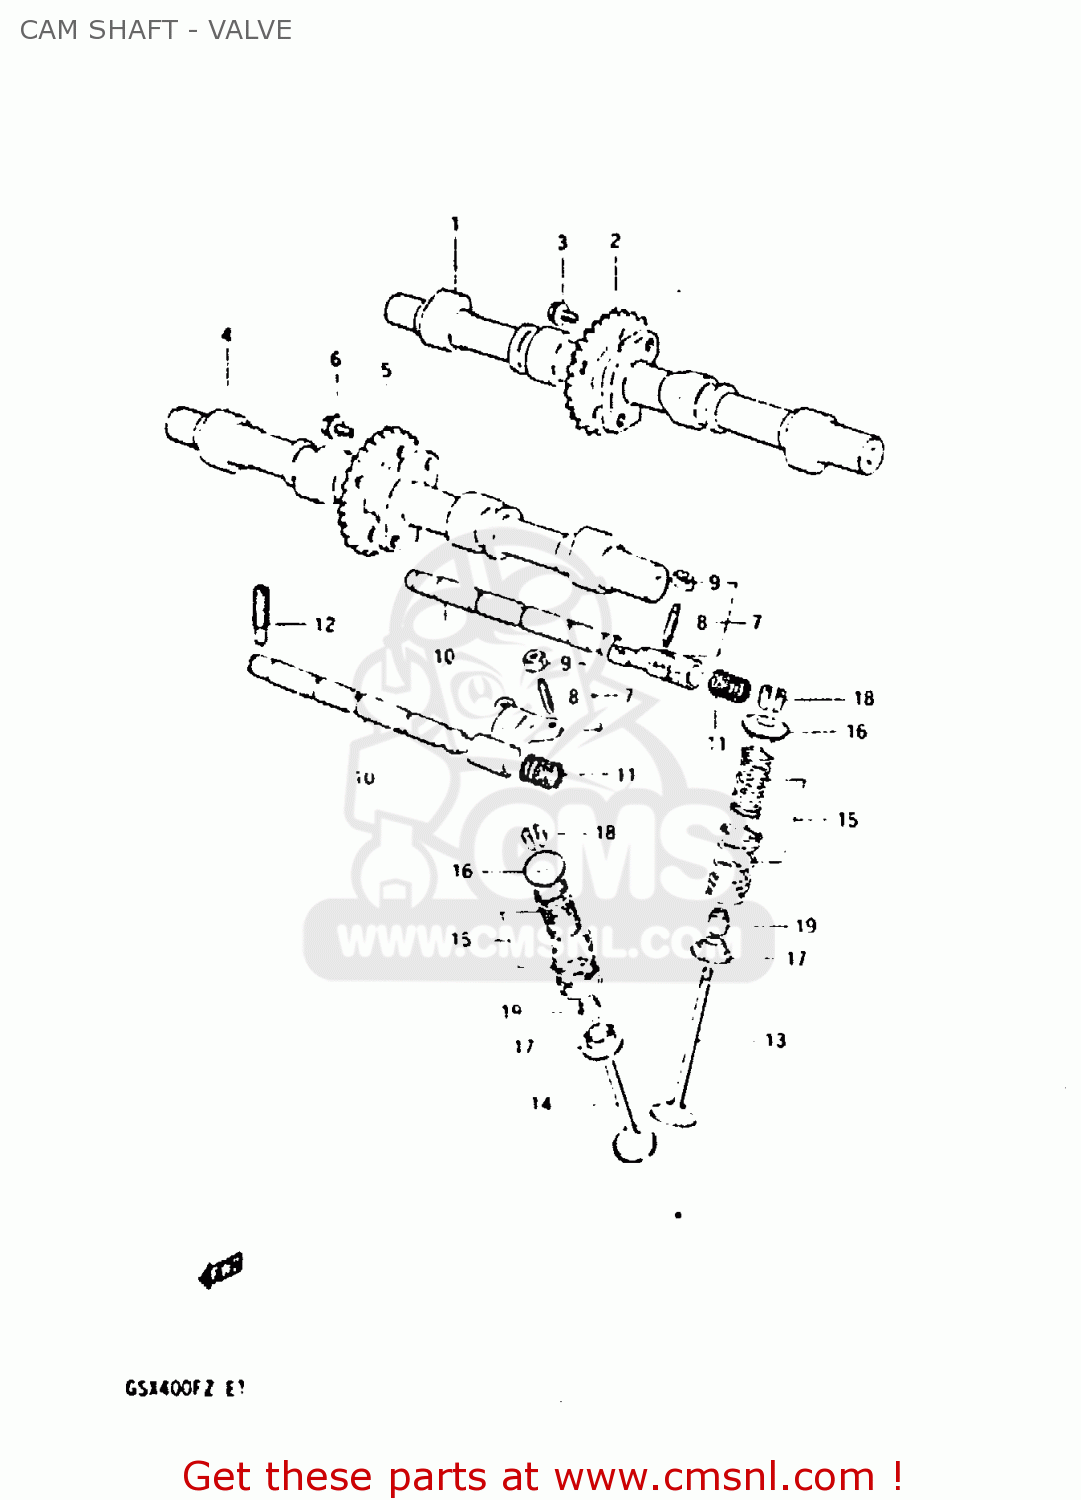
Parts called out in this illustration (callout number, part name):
1	CAM SHAFT, INTAKE
2	SPROCKET, EXHAUST CAM SHAFT
3	BOLT(7X11)
4	CAM SHAFT, EXHAUST
5	SPROCKET, EXHAUST CAM SHAFT
6	BOLT(7X11)
7	ARM, VALVE ROCKER
8	SCREW,TAPPET ADJUSTING
9	NUT,ADJUSTING
10	SHAFT, VALVE ROCKER ARM
11	SPRING
12	SCREW
13	VALVE,INTAKE
14	VALVE, EXHAUST
15	SPRING SET, VALVE
16	RETAINER,VALVE SPRING
17	SEAT,VALVE SPRING
18	COTTER VALVE
19	OIL SEAL
